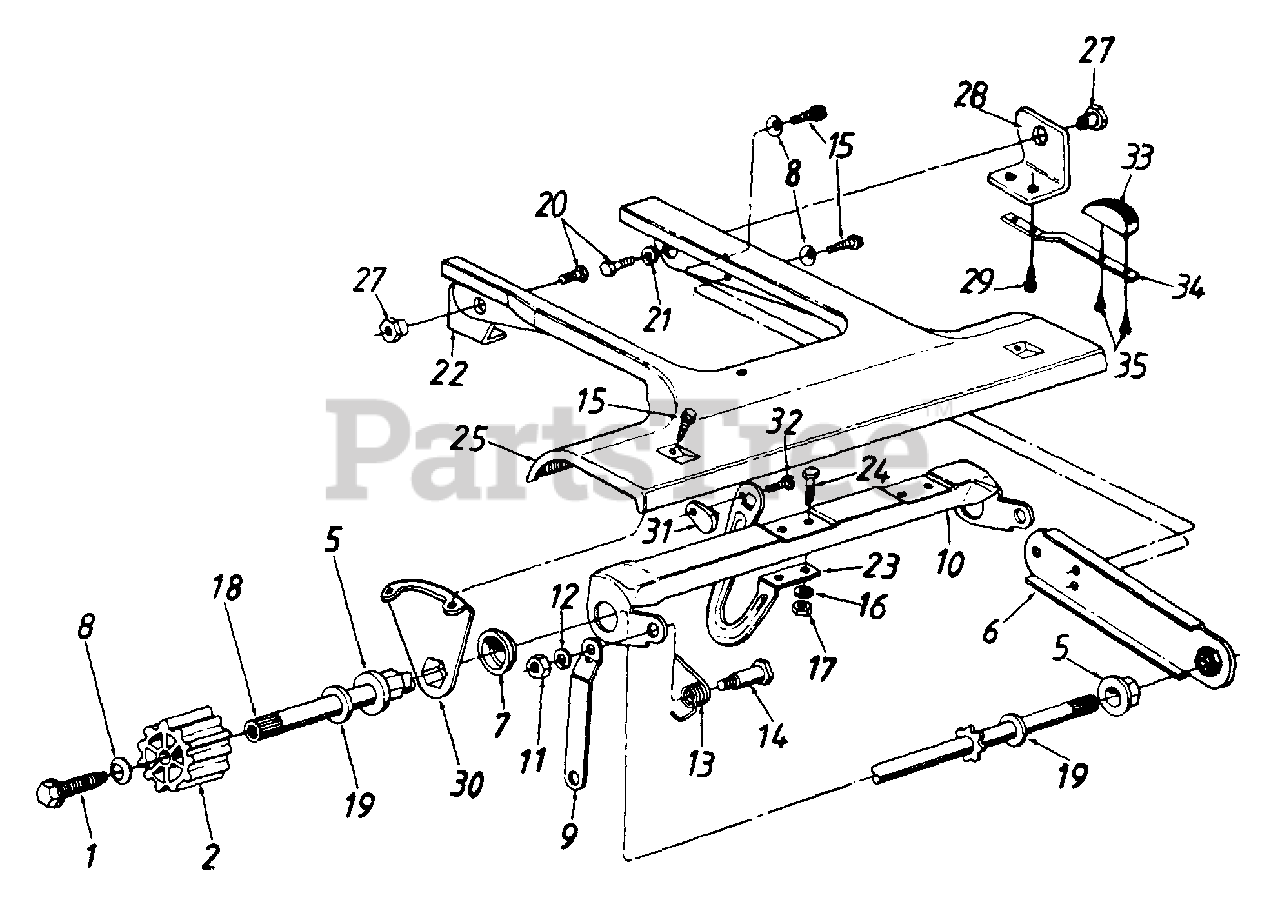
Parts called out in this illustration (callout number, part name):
1	Hex Scr. 1/4-20 x .75" Lg. (Gr. 5)
2	Wheel Drive Pinion
5	Hex Flange Brg..504" I.D.
8	Bell-Wash..265" 1.0. x .75" O.D.
9	Link 5.06" Lg.
10	Drive Engagement Cam
11	Hex Nut 5/16-18 Thd.
12	L-Wash. 5/16" I.D.
13	Torsion Spring - R.H.
14	Shoulder Bolt .437" Dia.
15	Hex Wash. Hd. AB-Tap Scr. 114 x .62" Lg.
16	L-Wash. 1/4" I.D.
17	Hex Nut 1/4-20 Thd.
18	Drive Shaft Ass'y.
19	Fl-Wash..531" I.D. x .93" O.D.
20	Hex Bolt 3/8-16 x .5" Lg.
21	L-Wash. 3/8" I.D.
32	Hex B-Tap Scr. #10 x .44" Lg.
33	Chain Tensioner
34	Cantilever Spring
35	Hex B-Tap Scr. #10 x .38" Lg.
